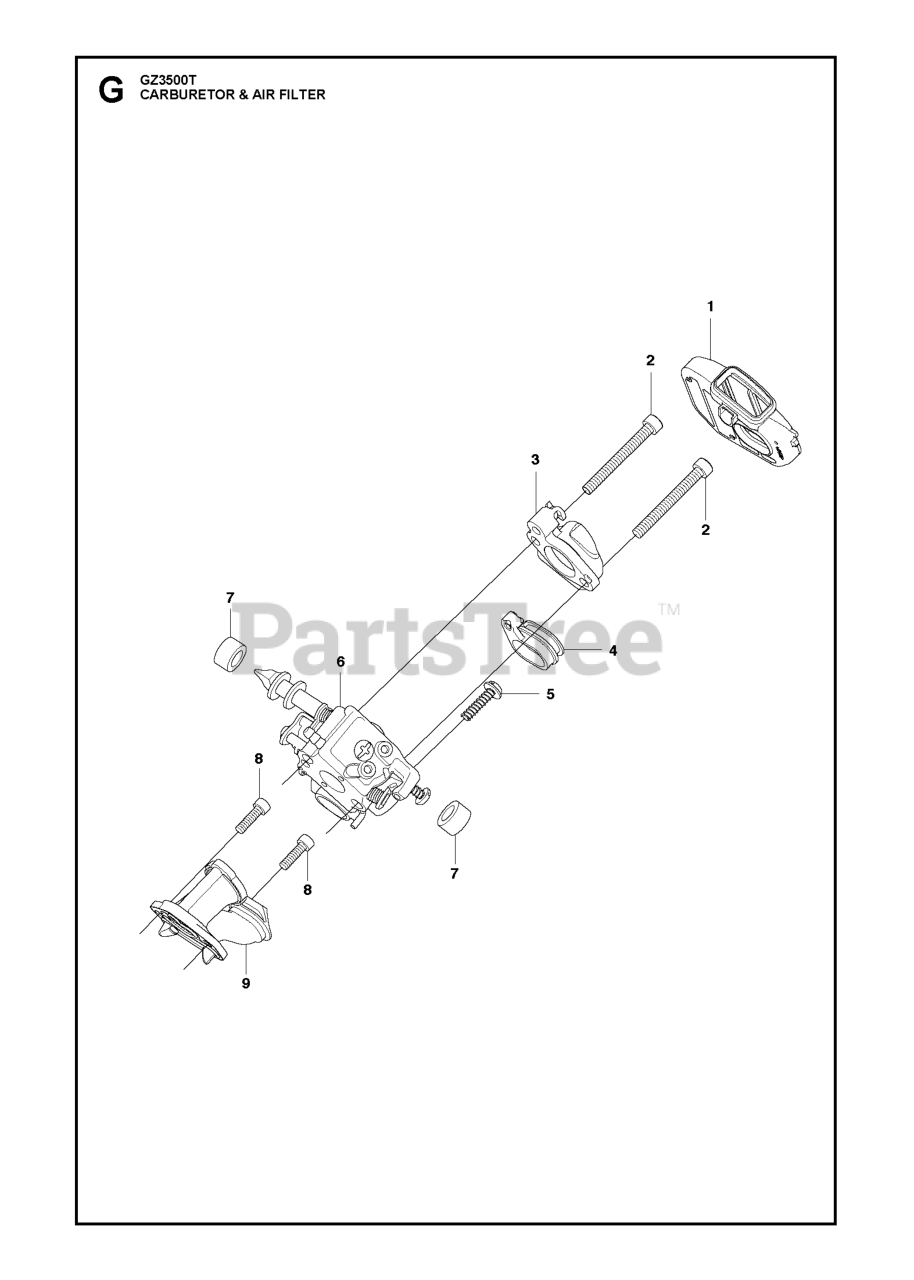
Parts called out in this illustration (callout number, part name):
2	BOLT
3	MANIFOLD
4	SEAL RPLS 848CE083G2
6	CARB ASSY
9	INLET PIPE
